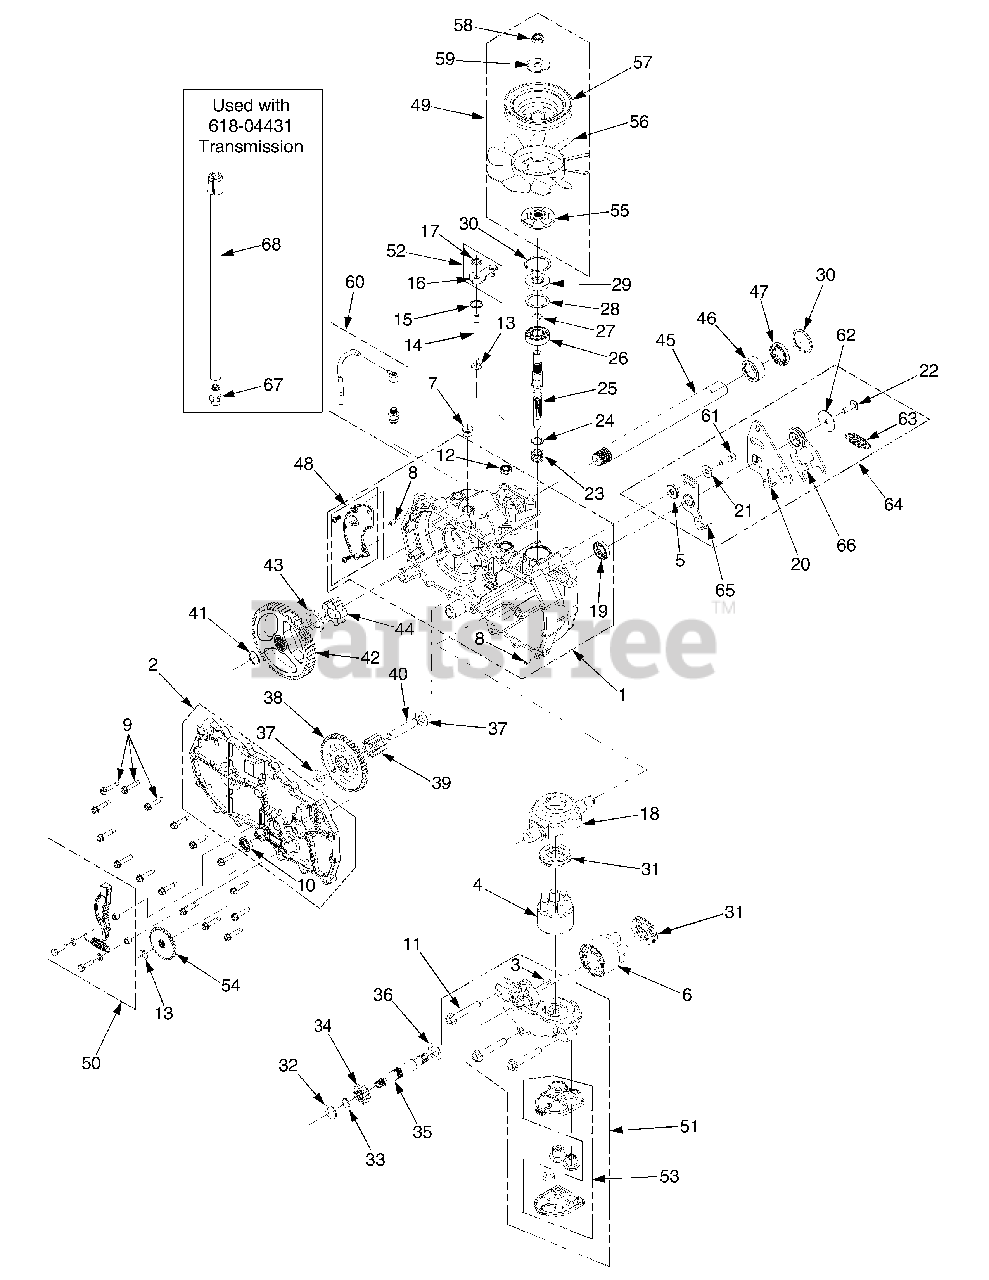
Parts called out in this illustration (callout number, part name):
1	Housing Assembly, Main LH .
2	Side Assembly, LH
3	Plate, Bypass
4	Pump Block Assembly
5	Spacer, .32 x 1.005
6	Motor Block Assembly
8	Pin, Stainless
9	Screw, Hex Self Tapping, 1/4-20 x 1.25
10	Seal, Brake
11	Bolt, Hex Flange, 3/8-24 x 2.5
12	Seal, Lip, .375 x .75 x .25
13	Ring, Retaining, .375 Ext.
14	Rod, Bypass
15	Ring, Retaining, .75 Int.
16	Arm, Bypass
17	Ring, Retaining, .375 Push ...
18	Swashplate, Trunnion
19	Seal, Lip, 18 x 32 x 7
20	Arm, Control LH
21	Washer, Flat, 11/32 x 7/8 x 1/16
22	Screw, 5/16-24 x 1.0
23	Spring, Compression
24	Washer, .591 x .787 x .04
25	Shaft, Input
26	Bearing, Ball, 17mm x 40 x 12
27	Ring, Wire Retaining, .561
29	Seal, Lip, 17 x 40 x 7
30	Ring, Retaining
31	Bearing, Thrust, 30 x 52 x 13
32	Washer, Flat, 5/8 x 1.0 x .05
33	Ring, Retaining
34	Gear, Pinion, 13T
35	Shaft, Motor
36	Washer, .71 x 1.16 x .04
37	Washer, HT, .5 x 1.0 x .032 ..
38	Gear, 10T/48T
39	Gear, Jackshaft, 10T
40	Pin, Jackshaft
41	Ring, Spiral Retaining
42	Gear, Bull, 52T
43	Washer, 1.018 x 1.571 x .105
44	Bearing, Sleeve
45	Shaft, Axle, 1.0 x 11.7
46	Bushing, Axle
47	Seal, Lip, 1.0 x 1.57 x .25
48	Kit, Expansion Plate, LH
49	Kit, Fan-Pulley
50	Kit, Brake Arm
51	Kit, Center Section-Filter LH
52	Kit, Bypass Arm
53	Kit, Filter
54	Disc, Brake Cog
55	Hub, Pulley
56	Fan, 7" 10 Blade
57	Pulley, 4.5
58	Nut, Hex Insert Lock, 1/2-20
59	Washer, OD Slotted
60	Kit, Breather
61	Screw, Hx Patch, 5/16-24 x 1.0
62	Washer, 1.5 x .34 x .062
63	Spring, Extension
64	Kit, Return AssemblyLH
65	Arm, Neutral RH
66	Assemble, Return, Bi-Direct.
67	Fitting, w/Cap
68	Hose Assembly
